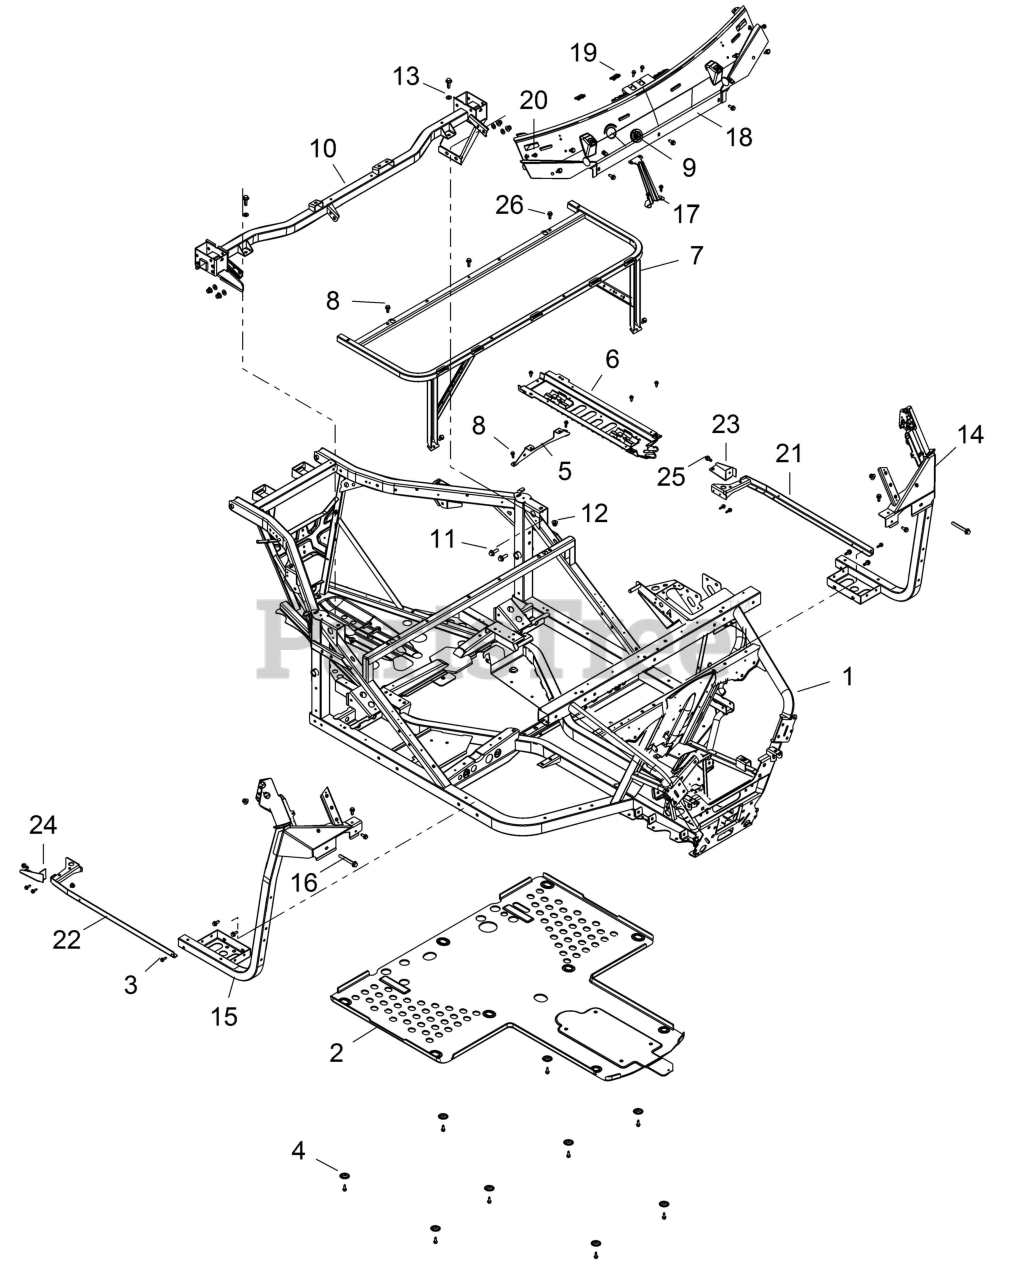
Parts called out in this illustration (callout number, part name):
1	WELD-FRAME,MAIN,ARNS,GAS,BLK
2	PLATE-SKID,BLK
3	SCR-M6X1.0X20,HXHD,FLG,TDFM,BL
4	WASHER SKID PLATE
5	BRKT-ROUTING TRAY,BLK
6	TRAY-ROUTING,BLK
7	WELD-CAB/SEAT BASE,BLK
8	BOLT-M8X1.25X20,HXFLG,TAP/R-OD
9	GROMMET-ELEC,CAB,SLIT
10	WELD-CAB SUPPORT,REAR,BLK
11	SCR-HXFL-M10X1.25X30 8.8 ZOD
12	NUT-M10X1.25,FLG,NYLOC-OLIVE D
13	WASHER,3/8 FW
14	WELD-FLOOR SUPPORT,LH,BLK
15	WELD-FLOOR SUPPORT,RH,BLK
16	SCR-HXFL-M10X1.25X80 8.8 ZOD
17	BRKT-PLATE,CTR,PIN MT,TTN
18	PLATE,WINDSHIELD MOUNT,LOW BLK
19	CLIP-U SPEED NUT
20	RIVET-TUFLOK,.315-.325X.787 (5
21	WELD-ROCKER,LH,BLK
22	WELD-ROCKER,RH,BLK
23	BRACKET,SUPPORT,ROCKER,LH BLCK
24	BRACKET,SUPPORT,ROCKER,RH BLCK
25	SCR-TXTH-M6X1.0X25 RIE
26	SCR, TFTX, M8X1.25 X 40
